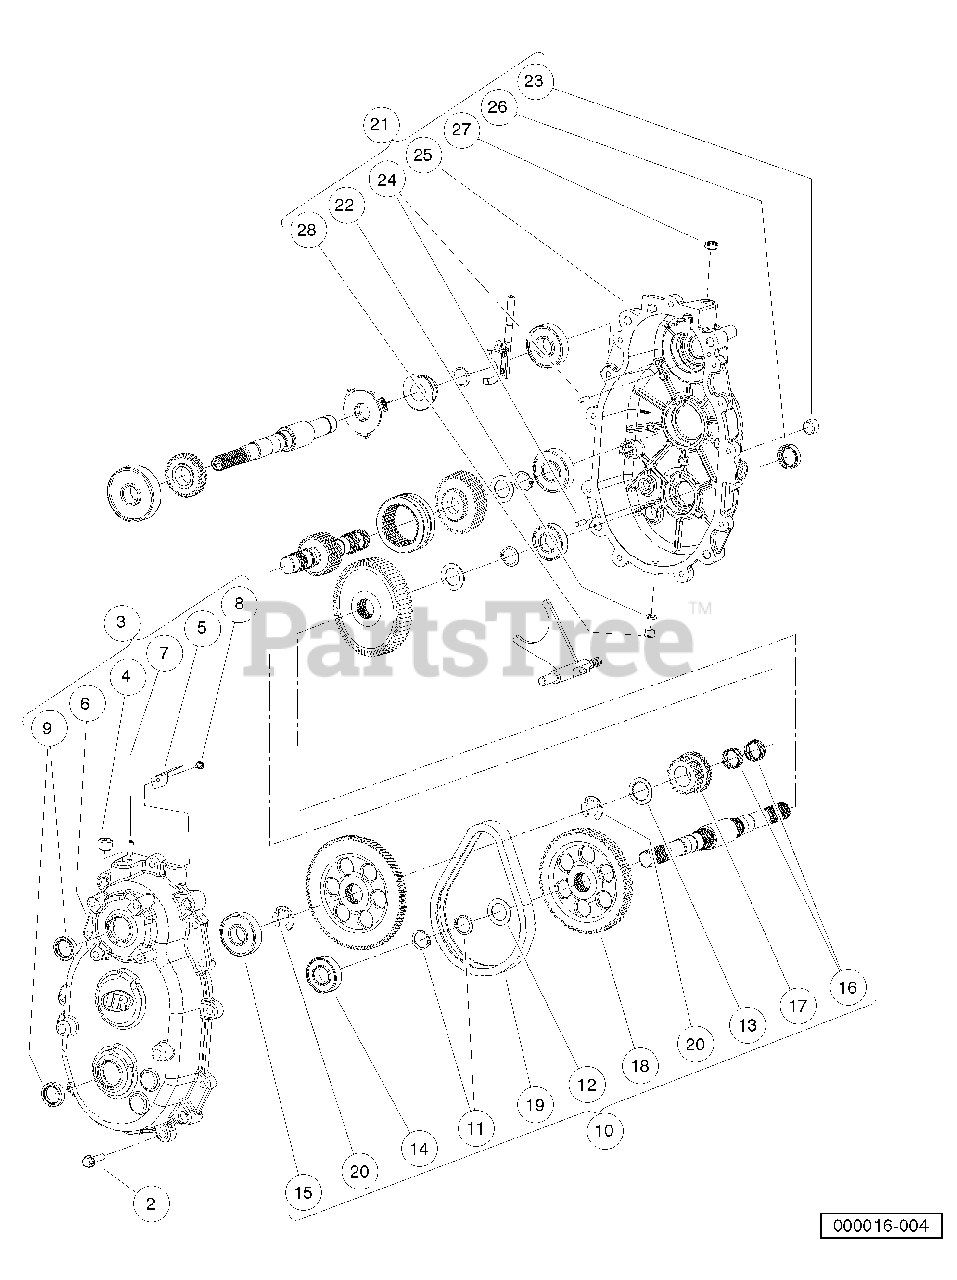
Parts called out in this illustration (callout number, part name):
1	Transmission, Parallel Shaft
2	Screw,hex Flange, M8 X 35
3	Asm, Gear Case, Rear
4	Plug, Square Skt, 1/12-14, Ptf
5	Oil, Deflector
6	Gearcase, Rear
7	Vent, Trans
8	Screw, Tapping # 10-24 X .375
9	Seal, Triple, 25 X 35 X 7.8
10	Kit, Reverse Gear Repair
11	Ring, Retaining, Basic External
12	Washer, Thrust, 1.007 X .062
13	Washer, 26.231 X 39.167 X 1.57
14	Bearing, Ball
15	Bearing, Ball
16	Bearing, Needle
20	Ring, Retaining, E-Ring
21	Asm, Case, Gear, Front
22	Washer, .625 X .382 X .60
23	Plug, Square Skt, 1/12-14, Ptf
24	Pin, Dowel, 6 X 20
25	Gearcase, Front
26	Seal, Triple, 25 X 35 X 7.8
27	Seal, Dual-Lip
28	Plug, 3/4-16
